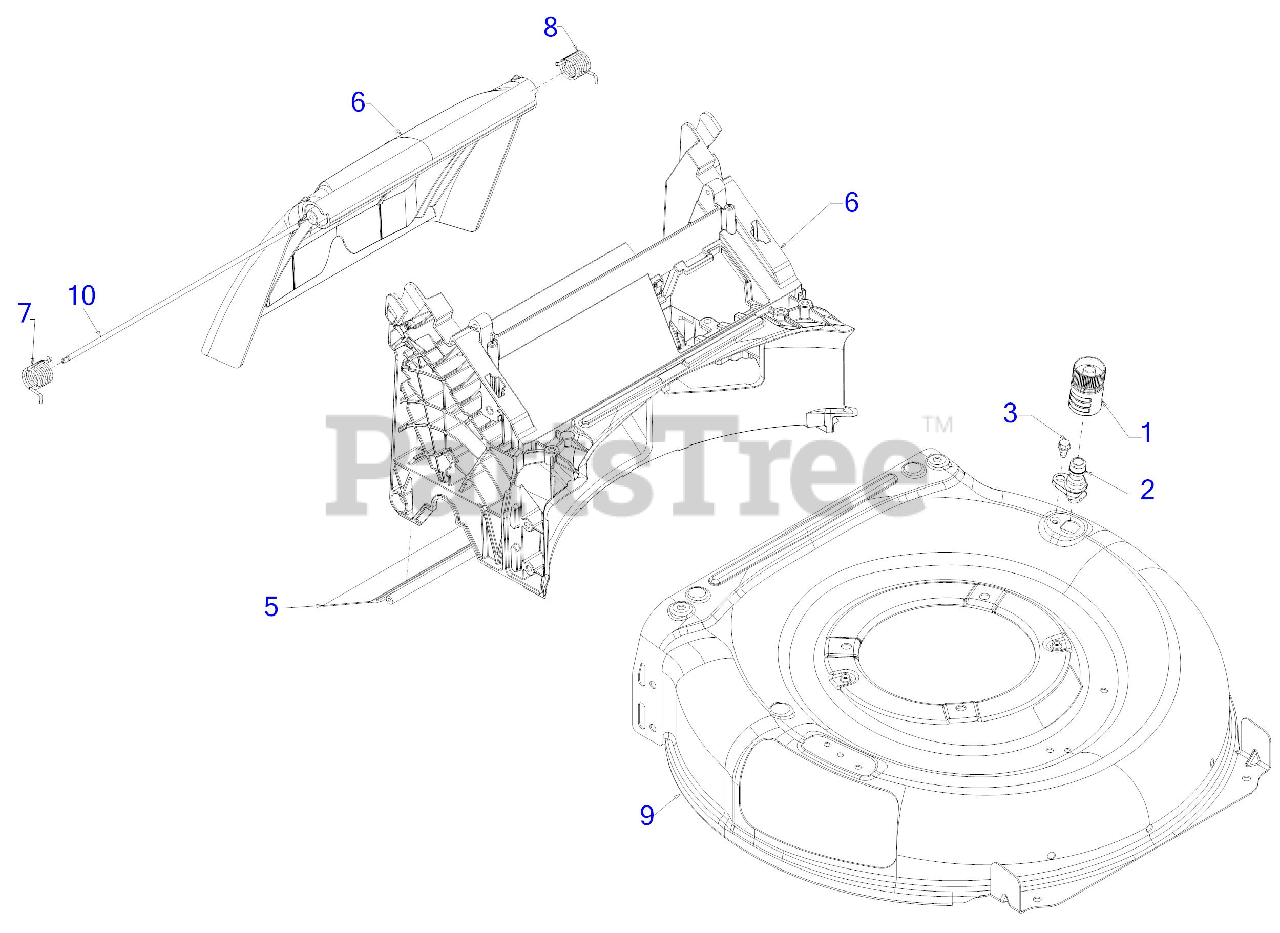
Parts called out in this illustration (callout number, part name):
1	WATER NOZZLE
2	DECK WASH NOZZLE
3	SHOULDER SCREW 1/4-20 x .50
4	MULCH PLUG
5	TRAILSHIELD
6	REAR BAFFLE ASSEMBLY
7	TORSION SPRING (RH)
8	TORSION SPRING (LH)
10	REAR DOOR PIVOT ROD
